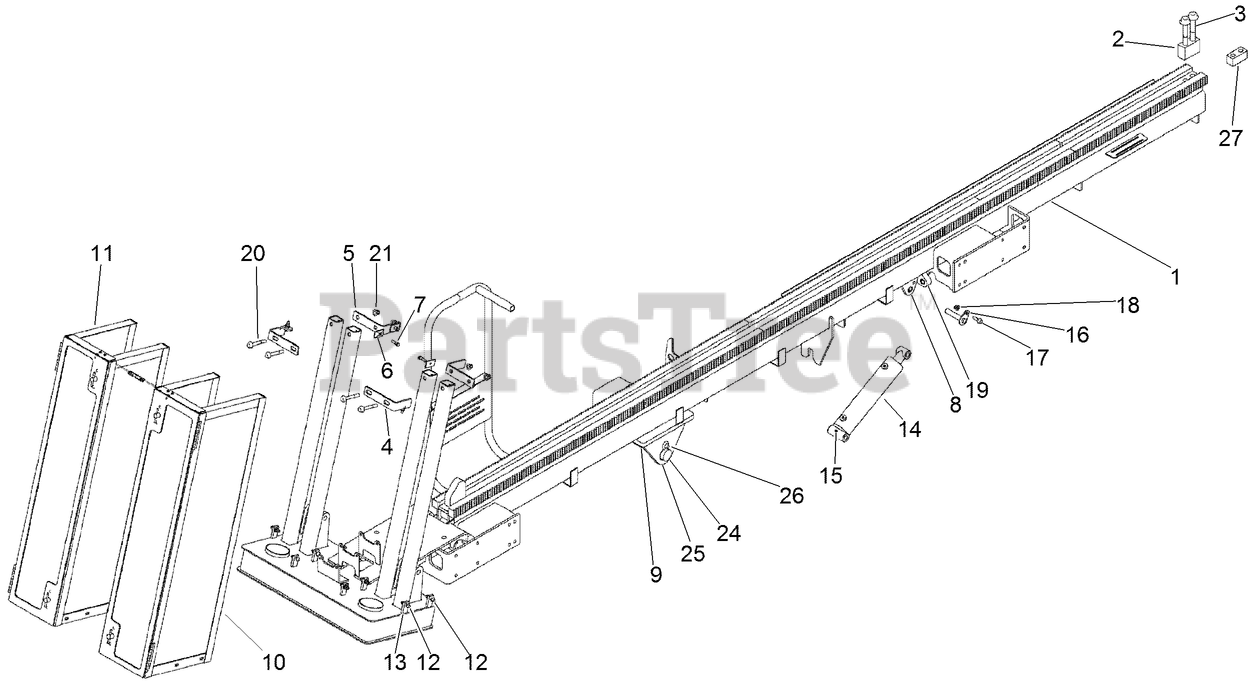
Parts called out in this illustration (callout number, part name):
1	WELDMENT - Thrust Frame
2	STOP BLOCK - Rear
3	SCREW-HHF
4	POST - Tie, Stakedown
5	HOLDER - Hose
6	PLATE-COVER, TWIN
7	BOLT-Hex, 5/16 NC x 1-1/4 inch
8	BUSHING-SPRG.75"IDX1.00"X .5"L
9	SPRING BUSHING - 2 ID x 2.25 OD x .75 Long
10	COVER - Stakedown, LH
11	COVER - Stakedown, RH
12	SCREW, METRIC FLANGE w/BODY - M8 x 35
13	NUT-TORQUE, PREVAILING
14	CYLINDER-HYDRAULIC
15	FITTING-Lube 1/4-28 Tpr SAE-LT .54 Long
16	PIN-FLAG
17	SCREW-HHF
18	NUT-FLANGE, NYLOCK
19	BUSHING-SPRING
20	SCREW, METRIC FLANGE w/BODY-M12 x 90
21	NUT-HHF, LOCK
24	PIN ASSEMBLY - Boom
25	PIN-RETAINER
26	SCREW-FLANGE
27	BLOCK - Tapped
